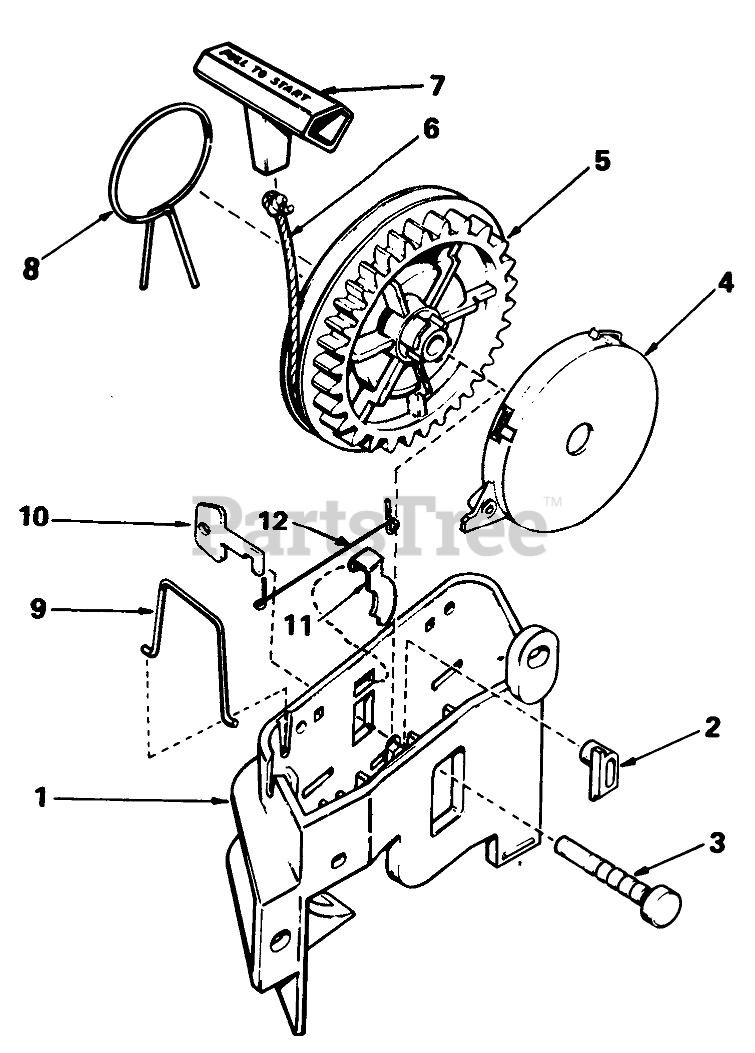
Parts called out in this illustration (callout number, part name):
1	Bracket Starter
2	Pawl, Locking Not used on all engine models)
3	Pin-Pulley
4	Spring Assy., Rewind (Incl. Ref. #3)
5	Pulley
6	Rope-Starter (98 cut to length)
7	Handle-Starter
8	Spring, Brake
9	Clip-Rope
10	Key (Not Used On All Engine Models
11	Pawl, Starter
12	Spring, Pawl
